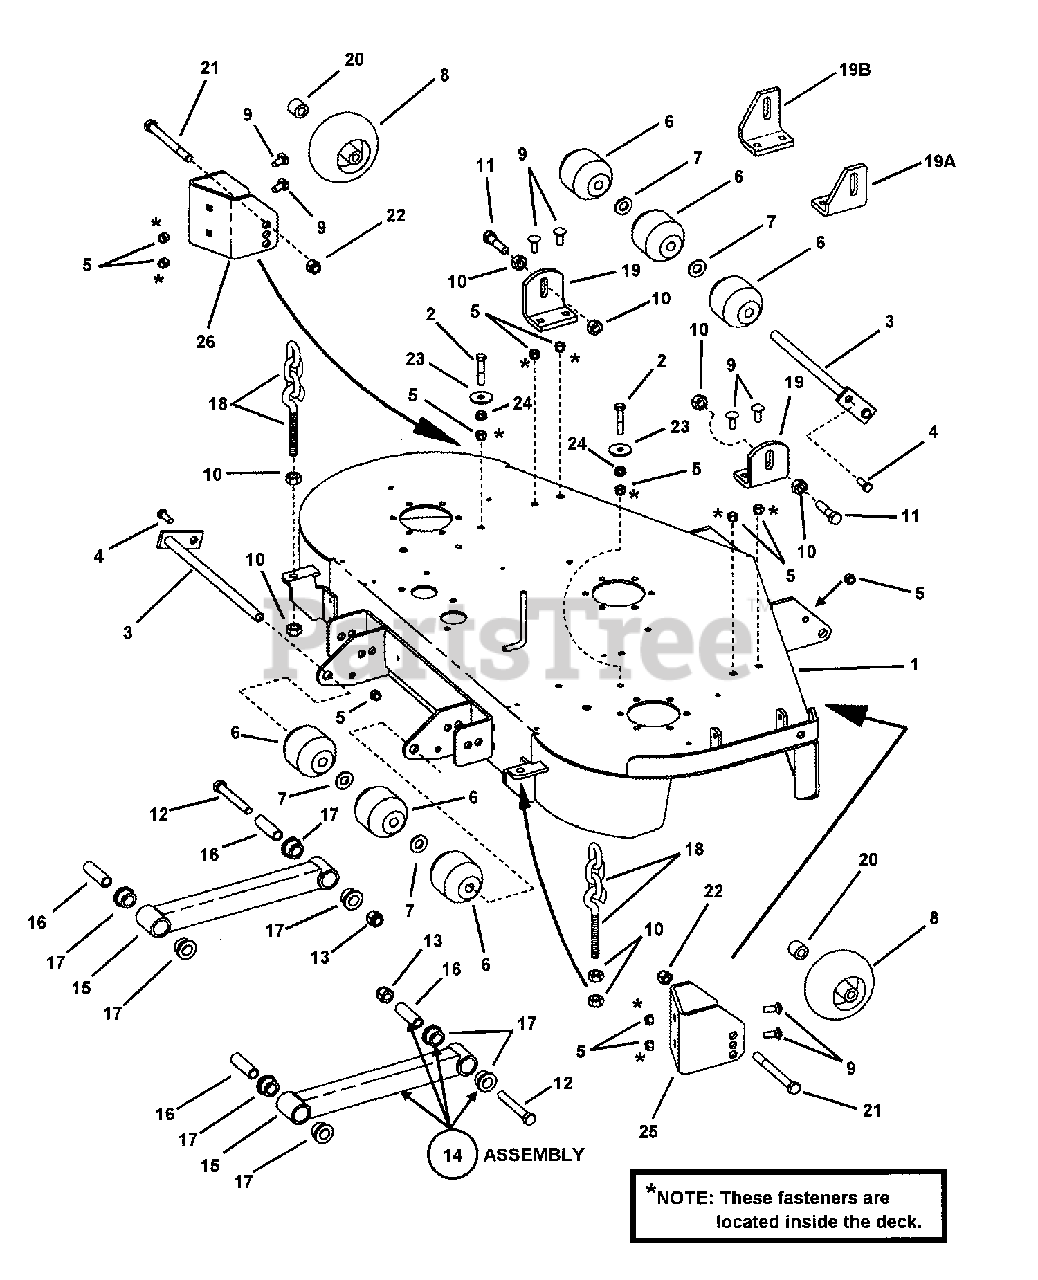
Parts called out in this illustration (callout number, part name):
1	WELDMENT, 52" Deck
2	BOLT, 3/8-16 X 2, GD5, CZ
3	WELDMENT Pivot Pin
4	BOLT, 3/8-16 X 1" GD5 CZ
5	NUT, 3/8-16 HEX NYLON LOCK
6	ROLLER Low Density Polyethylene
7	WASHER, 5/8" Flat SAE
8	GAUGE WHEEL, Polyethylene
9	BOLT, 3/8-16 x 1" Square Neck Carriage GR 5
10	NUT, 1/2-13 HEX
11	SCREW, 1/2-13 x 2" Hex Head Cap, GR5
12	BOLT, 1/2-13 x 3-3/4" Hex Head Cap, GR5
13	NUT, 1/2-13 HEX NYLON LOCK
15	WELDMENT, Pusher Bar
16	SLEEVE - Suspension
17	BUSHING - Suspension
18	ASSEMBLY, Chain & Eyebolt (see Front Frame Assy page, item 63)
19	BRACKET, Front Deck Lift
19A	BRACKET, Front Deck Hanger R. H.
19B	BRACKET, Front Deck Hanger L. H.
20	SPACER, Gauge Wheel
21	BOLT, 1/2-13 X 5 GD5 YZ
22	NUT, 1/2-13 HEX NYLON LOCK
23	WASHER, .406 x 1.50 x .120 Flat
24	NUT, 3/8-16 HEX SERRATED FLANGE
25	WHEEL BRACKET Front Right
26	WHEEL BRACKET Front Left
